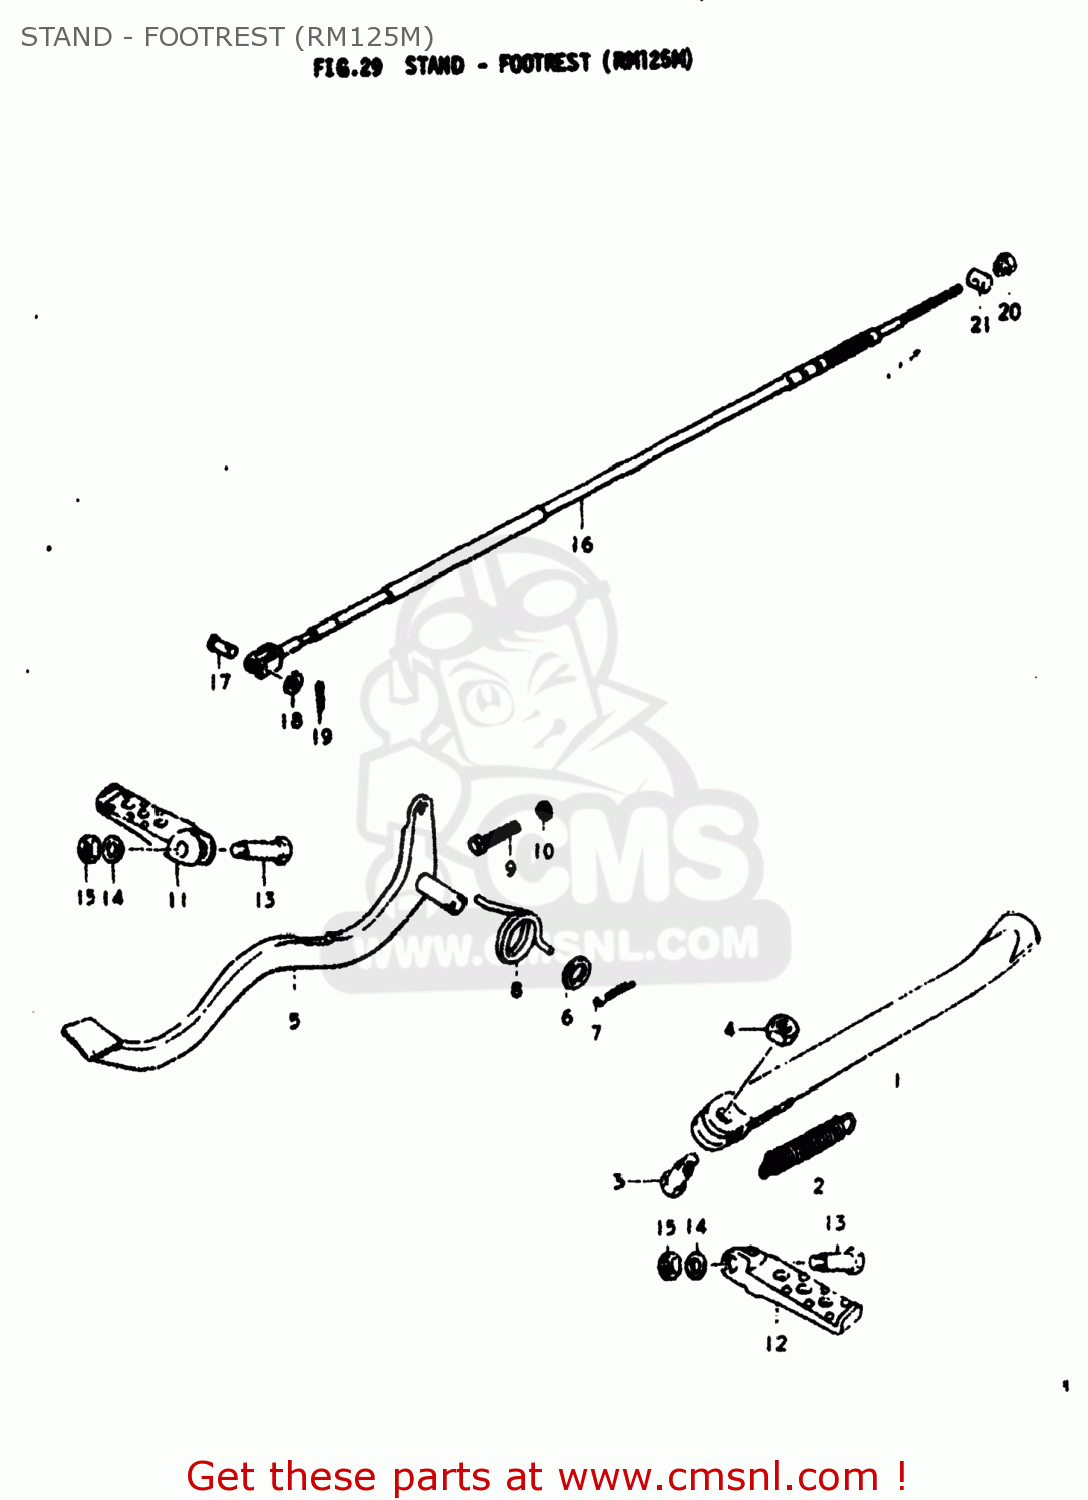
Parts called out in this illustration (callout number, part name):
1	STAND,SIDE
2	SPRING
3	BOLT(10X30)
4	NUT
5	PEDAL,BRAKE
6	WASHER
7	PIN 30X20
8	SPRING
9	BOLT
10	NUT
11	BAR,FRONT FOOTREST
12	BAR,FOOTREST,LEFT
13	BOLT
14	WASHER
15	NUT
16	CABLE ASSEMBLY,REAR BRAKE
17	PIN(L:17.5)
18	WASHER
19	PIN
20	NUT
21	PIN(11X18)
